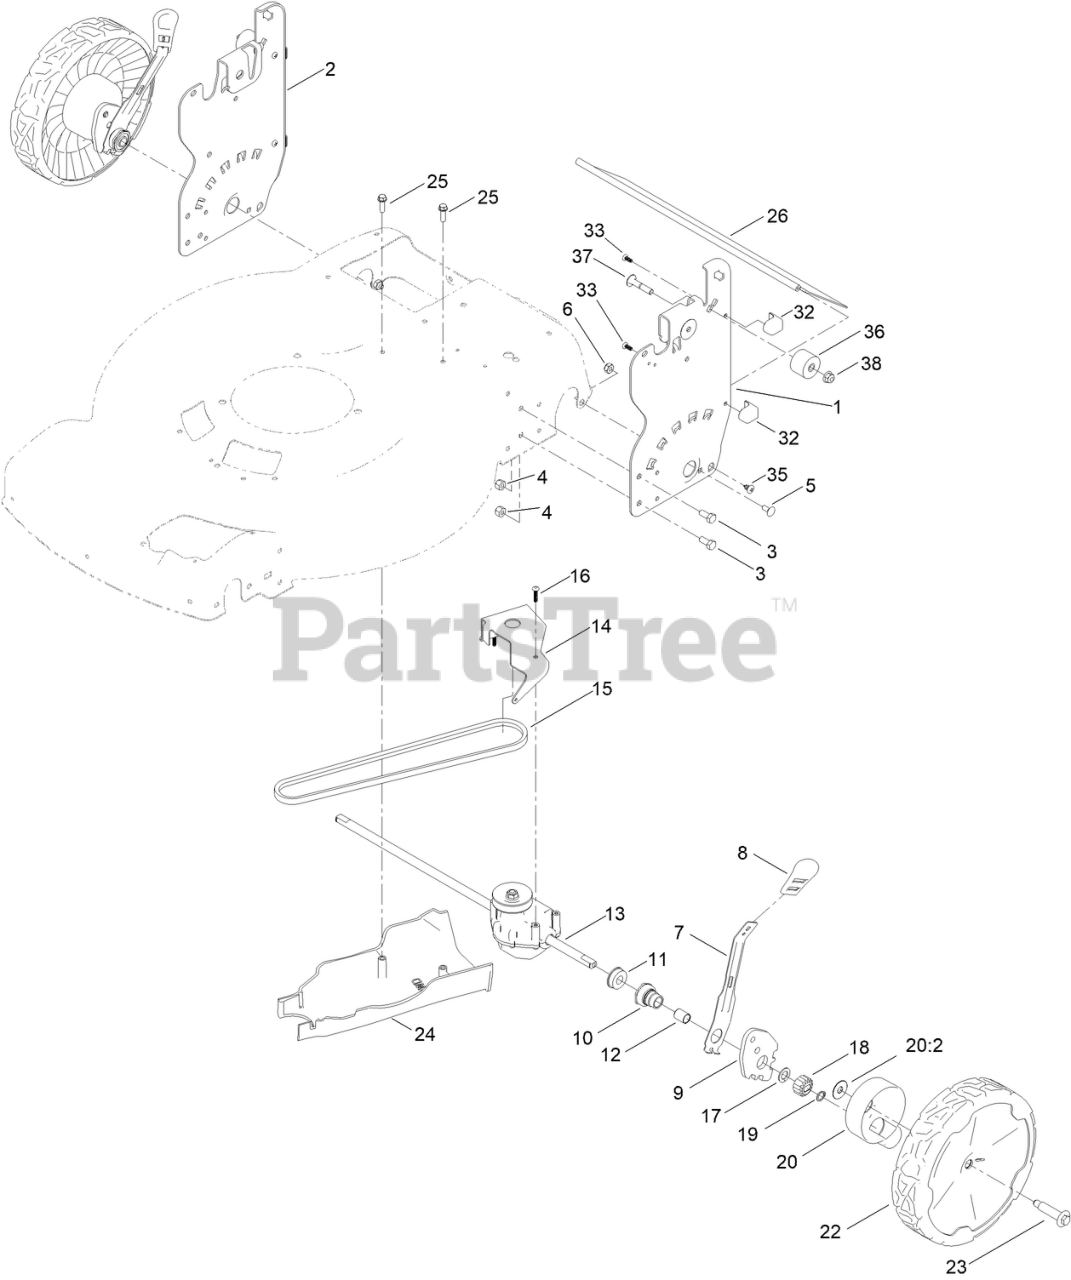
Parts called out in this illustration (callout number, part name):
1	PLATE-HOC, LH (ISO)
2	PLATE-HOC, RH (ISO)
3	SCREW-HH
4	NUT-LOCK, NI
5	SCREW-CARR
6	NUT-LOCK, NI
7	ARM-SPRING
8	KNOB-HOC
9	ARM-PIVOT, REAR
10	RETAINER-BUSHING, HOC
11	BEARING-BALL
12	BUSHING-SLEEVE
13	TRANSMISSION-RWD
14	BRACKET-TRANSMISSION
15	V-BELT
16	SCREW-PLASTITE
17	WASHER-THRUST
18	GEAR-PINION, 15T
19	RING-RETAINING
20	ASM-COVER, GEAR (DK GRAY)
20:2	WASHER-STEPPED
22	ASM-9.65" WHEEL, GEARED
23	WHEEL BOLT
24	COVER-BELT, RWD
25	SCREW-HWH
26	SHIELD-TRAILING
32	PAD-SMART STOW
33	SCREW-PLASTITE
35	SCREW-PTH
36	BUMPER-ISOLATOR
37	SCREW-CARR-SPCL
38	NUT-HF, NI
